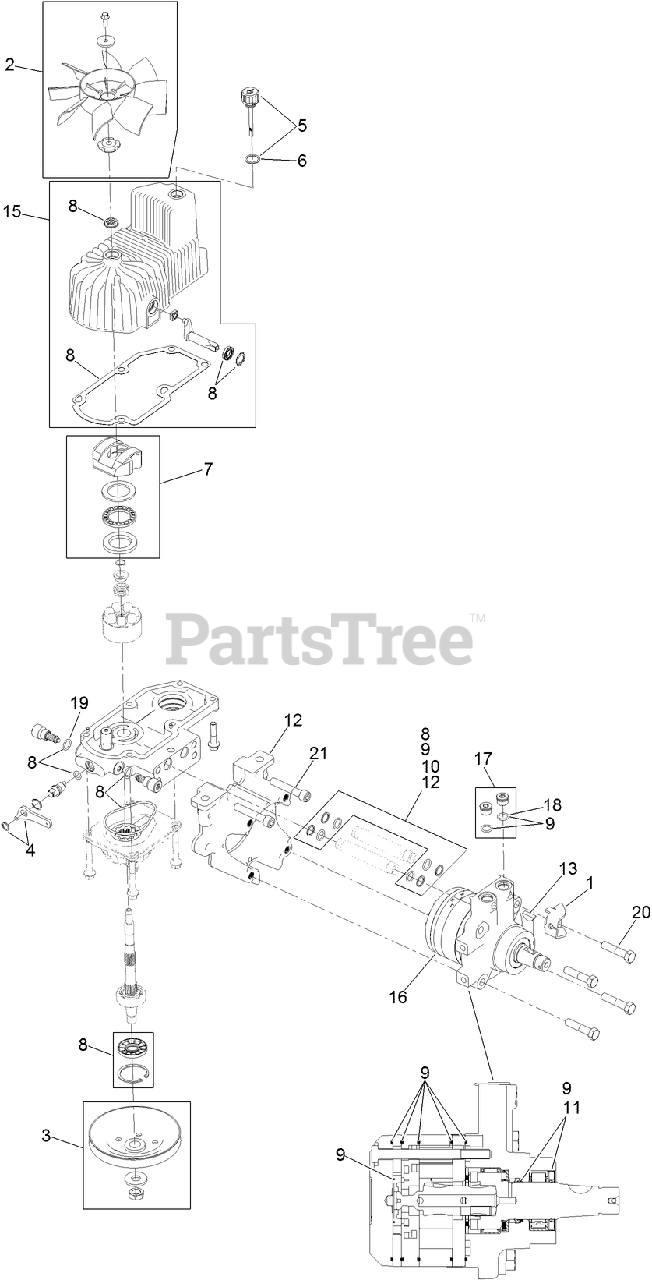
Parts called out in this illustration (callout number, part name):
1	BRACKET-ANCHOR, CABLE
2	FAN KIT
3	PULLEY KIT
4	HANDLE-BYPASS VALVE, HYDRO
5	DIPSTICK-HYDRO W/GASKET
6	GASKET-DIPSTICK, HYDRO
7	SWASH BLOCK KIT
8	PUMP SEAL KIT
9	MOTOR SEAL KIT
10	TUBE SEAL KIT
11	OUTPUT SHAFT SEAL KIT
12	NOSE CUP-UHT
13	KEY-WOODRUFF
15	Housing-LH
16	MOTOR-HYDRAULIC LH 240CC
17	MAGNETIC PLUGS SERVICE KIT
18	O-RING
19	O-RING-CHECK VALVE
20	SCREW HH
21	SCREW-HSH
